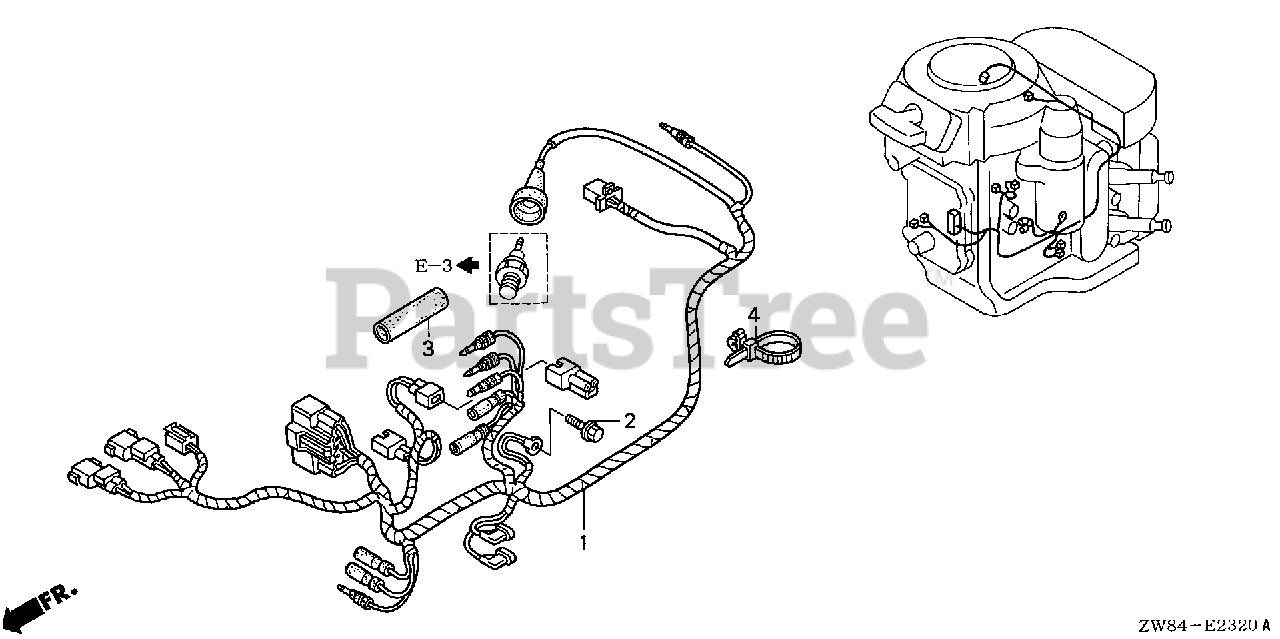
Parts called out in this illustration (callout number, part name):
1	WIRE HARNESS ASSY.
2	BOLT, FLANGE (6X12)
3	TUBE, RUBBER (12X14)
4	BAND, WIRE
